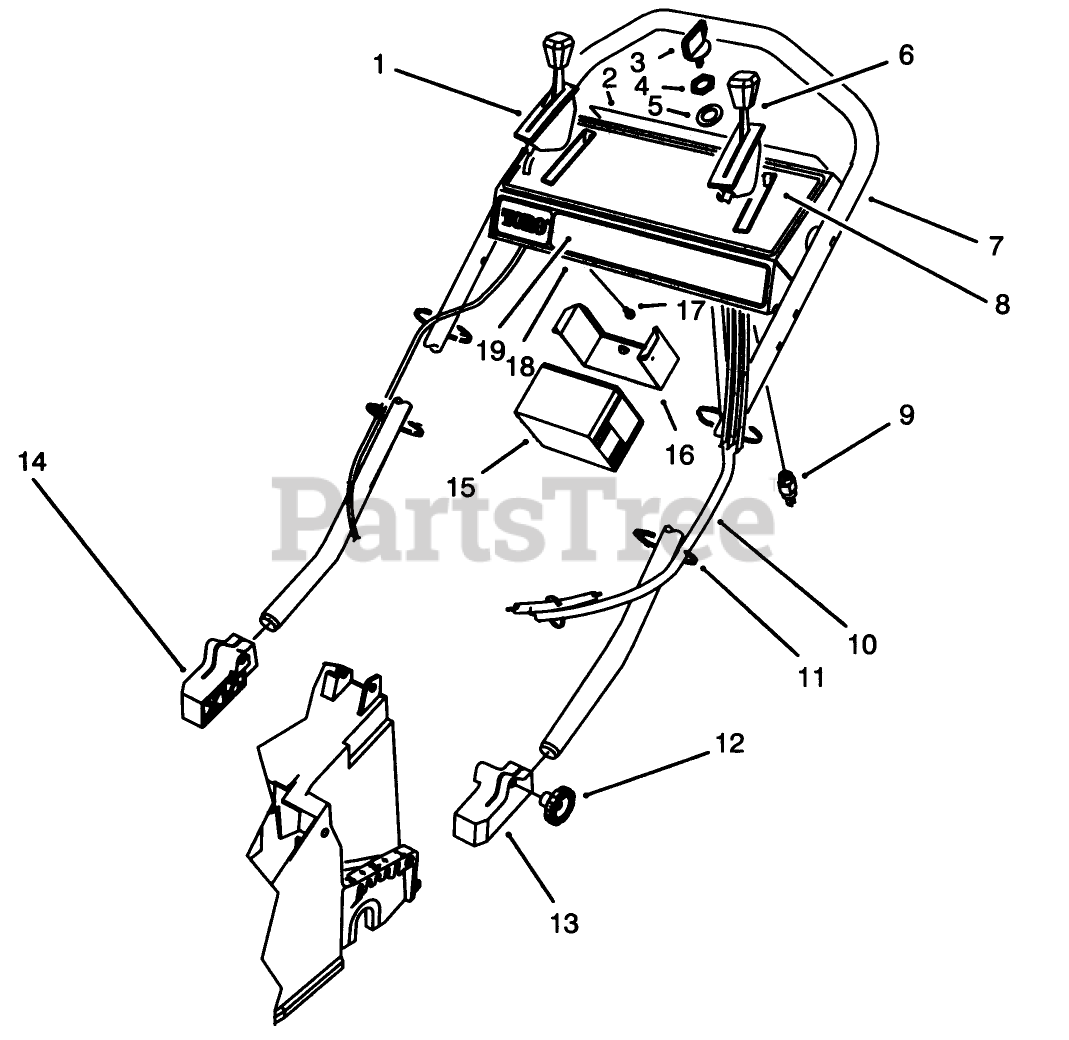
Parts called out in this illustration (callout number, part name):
1	GROUND SPEED CONTROL
3	KEY-IGNITION
4	NUT-HH
5	WASHER-LOCK
6	THROTTLE CONTROL
9	STARTER SWITCH ASM
11	TIE-CABLE
13	MOUNT-HANDLE, LH
14	MOUNT-HANDLE, RH
17	SCREW-HWHTF
18	PANEL W/DECALS
19	DECAL - PANEL KEY
